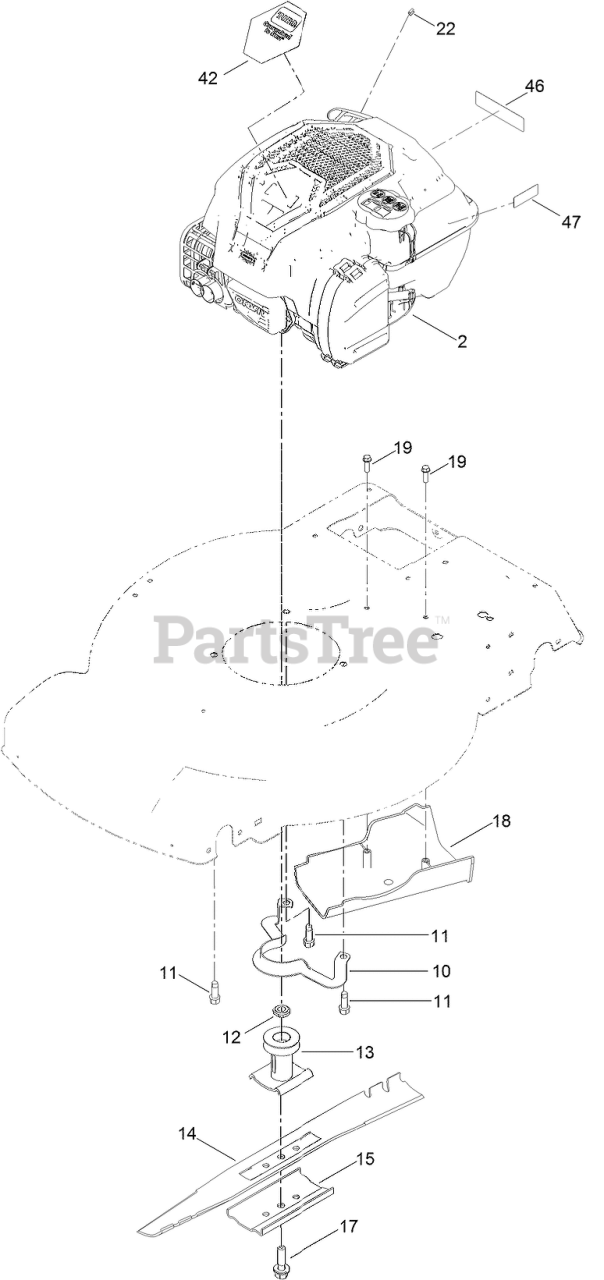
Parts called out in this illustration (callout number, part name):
10	GUIDE-BELT
11	SCREW-TAPTITE
12	SPACER-DRIVER
13	DRIVER-BLADE
14	BLADE-22 INCH
15	SUPPORT-BLADE
17	BOLT-BLADE
18	COVER-BELT
19	SCREW-HWH
22	STOP-ROPE
42	DECAL-SHROUD
46	DECAL-ARRESTOR, SPARK
47	DECAL-LEVEL, FUEL
